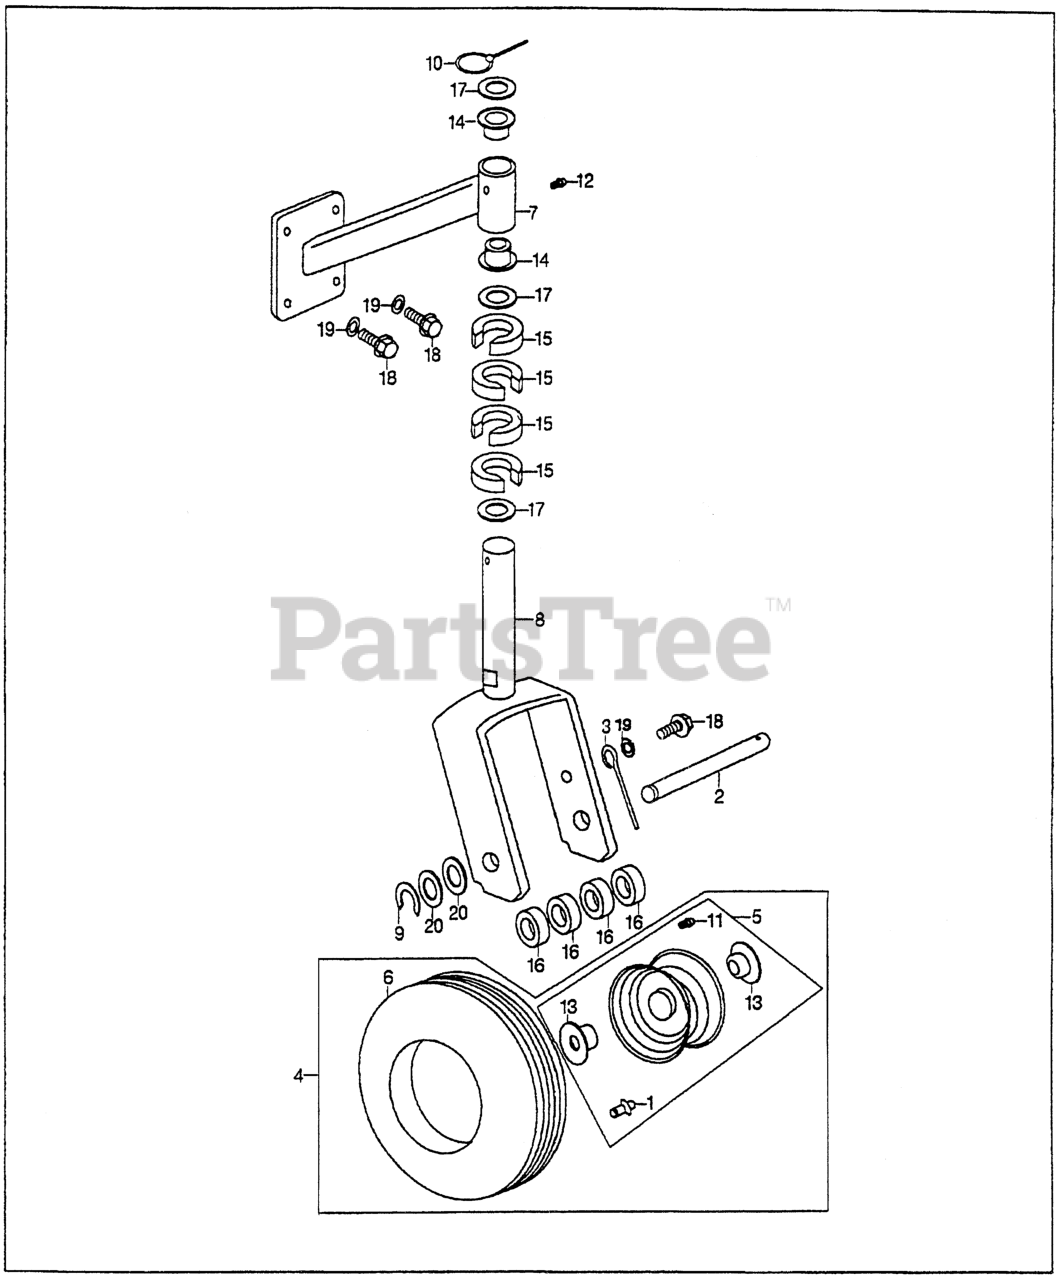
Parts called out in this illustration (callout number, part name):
1	VALVE, RIM
2	SHAFT, STEEL
4	WHEEL ASSY.
5	WHEEL ASSY., FR.
7	BRACKET, GAUGE ROLLER
8	ARM, GAUGE ROLLER
9	E-RING (3/4")
10	QUICK CLIP
11	NIPPLE, GREASE
12	NIPPLE, GREASE
13	BEARING, WHEEL
14	BUSHING, CASTER TUBE
15	COLLAR, CASTER TUBE
16	COLLAR, FR. WHEEL
17	BUSHING (1")
20	BUSHING, MACH (3/4")
